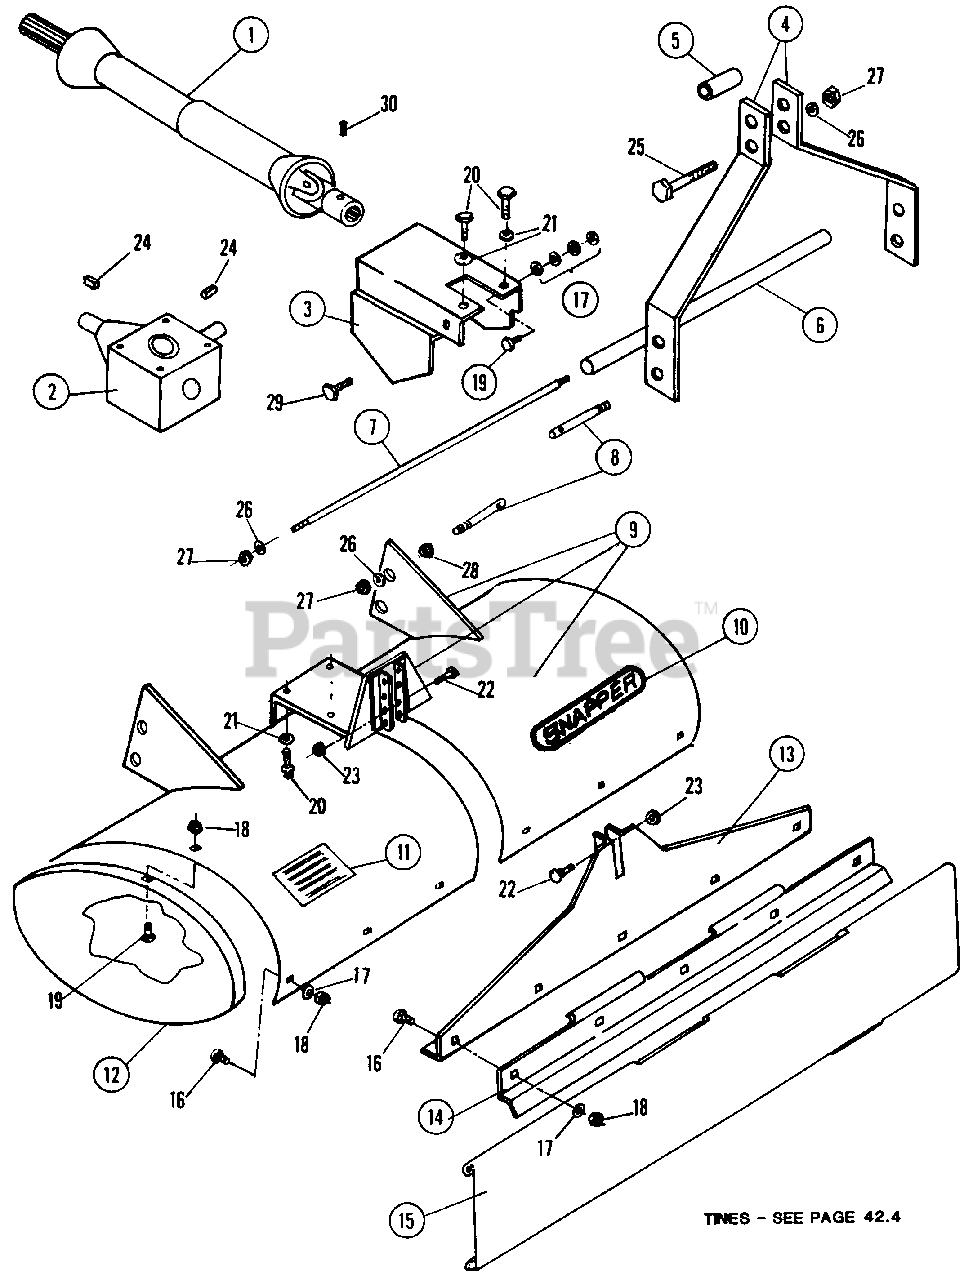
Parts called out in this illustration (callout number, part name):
1	SHAFT, P.T.O.
2	GEAR BOX - COMPLETE
3	SHIELD, P.T.O. EXTENSION
4	BAR-MAST
5	SPACER, MAST
6	TUBE, LOWER TIE
7	ROD, LOWER TIE
8	PIN, LOWER LINK
9	SHROUD ASSEMBLY
10	DECAL, SNAPPER
11	DECAL, CAUTION
12	COVER, SHROUD END
13	BRACE, SHROUD
14	HINGE, LEVEL BLADE
15	LEVEL BLADE
16	BOLT, 5/16-18 x 3/4 CARRIAGE
17	WASHER, 5/16 SAE
18	LOCKNUT, 5/16-18 HEX
19	BOLT, 5/16-18 x 1/2 CARRIAGE
20	BOLT, 5/16-18 x 3/4 HEX HEAD
21	LOCKWASHER, 5/16 MEDIUM
22	BOLT, 1/4-20 x 1-1/4 CARRIAGE
23	LOCKNUT, 1/4-20 HEX
24	KEY, 3/16x3/16x1"
25	BOLT, 5/8-11 x 2-3/4 HEX HEAD
26	LOCKWASHER 5/8 MEDIUM
27	NUT, 5/8-11 HEX
28	JAM-NUT, 5/8-11 HEX
29	BOLT, 1/4-20 x 2 HEX HEAD
30	SETSCREW, HEX SOCKET 5/16-18 x 1/2 Locking (Use 90848 or 91995)
